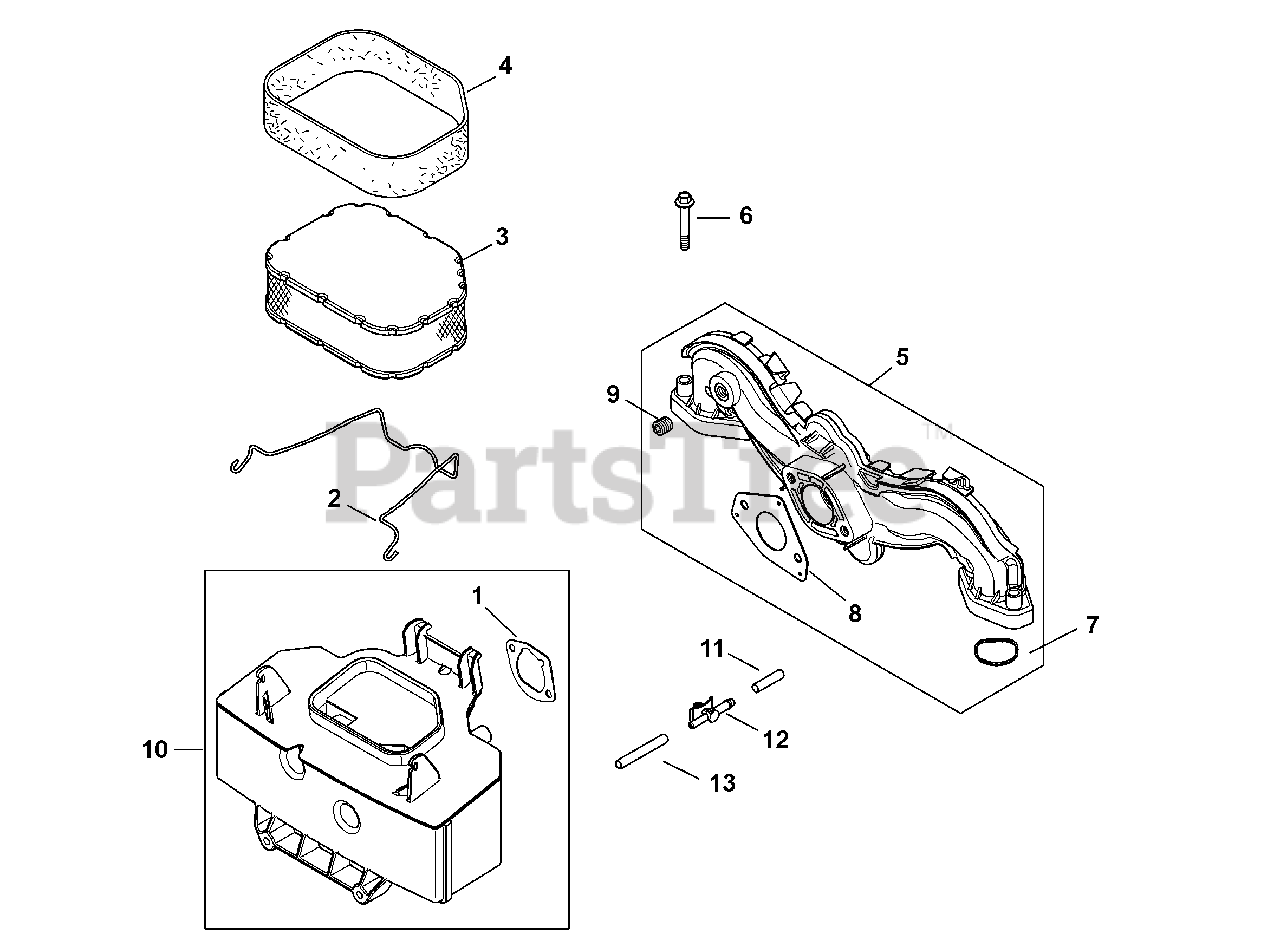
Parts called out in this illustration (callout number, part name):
1	Air Cleaner Base Gasket
2	Air Cleaner Element Latch
3	Air Filter & Pre-Cleaner Elements
4	Pre-Cleaner Element
5	Intake Manifold Kit
6	Flg. Screw, M6 x 1.0 x 40
7	O-Ring, Intake Port
8	Carburetor Gasket
9	Pipe Plug, 1/8"
10	Air Cleaner Base
12	Evaporative Connector
13	Evaporative Hose, 20"
